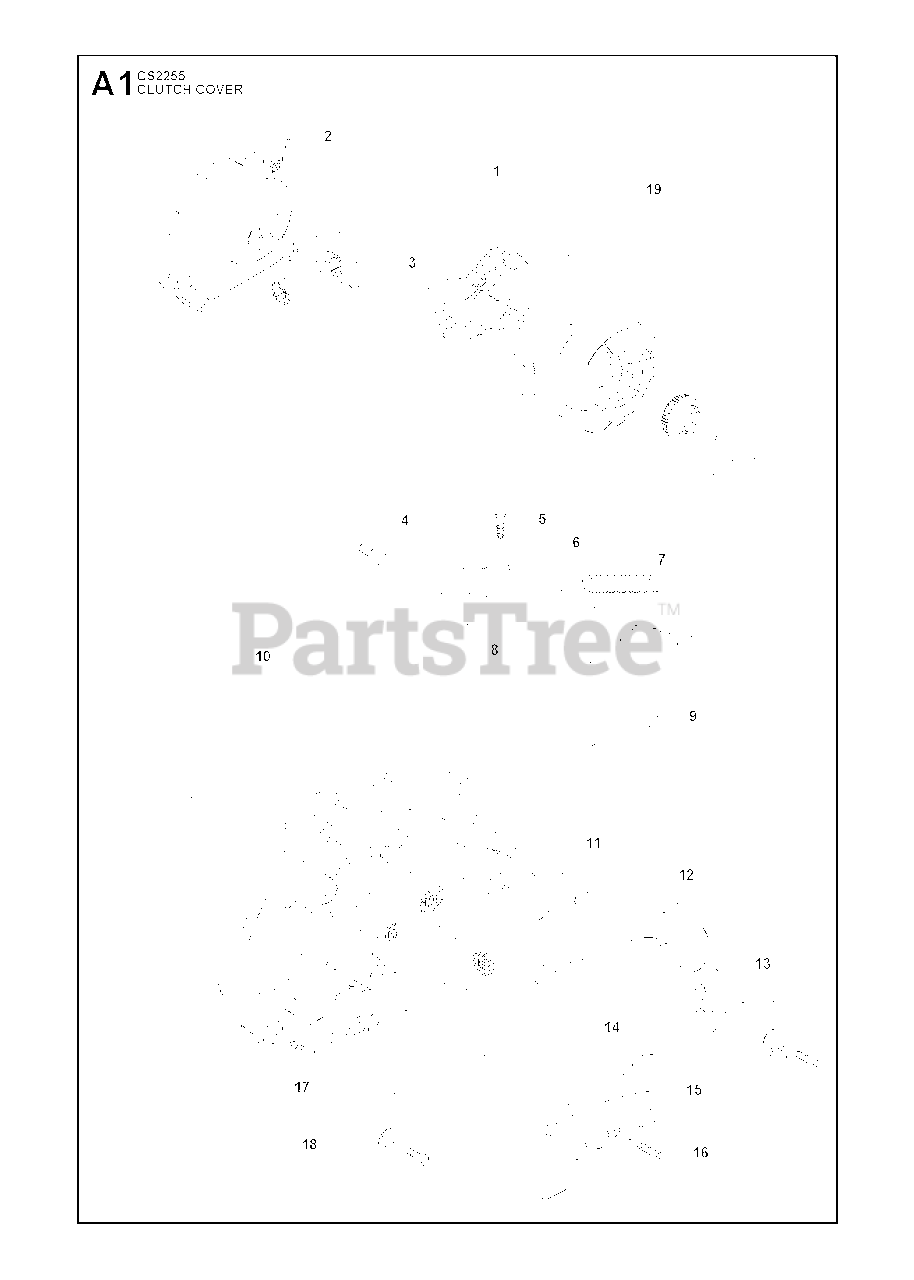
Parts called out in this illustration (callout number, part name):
1	CLUTCH COVER ASSY
3	CHAIN TENSIONER WHEEL
4	PIN
5	SCREW
6	JOINT
7	SPRING
8	E-RING 4
9	BRAKE BAND
10	LABEL
11	SLEEVE
12	COVER, CHAIN BRAKE
13	WEAR GUARD, CHAIN
14	CHAIN TENSIONER SCREW, COMP.
15	PLATE
16	SCREW
17	SLEEVE
18	%COVER
